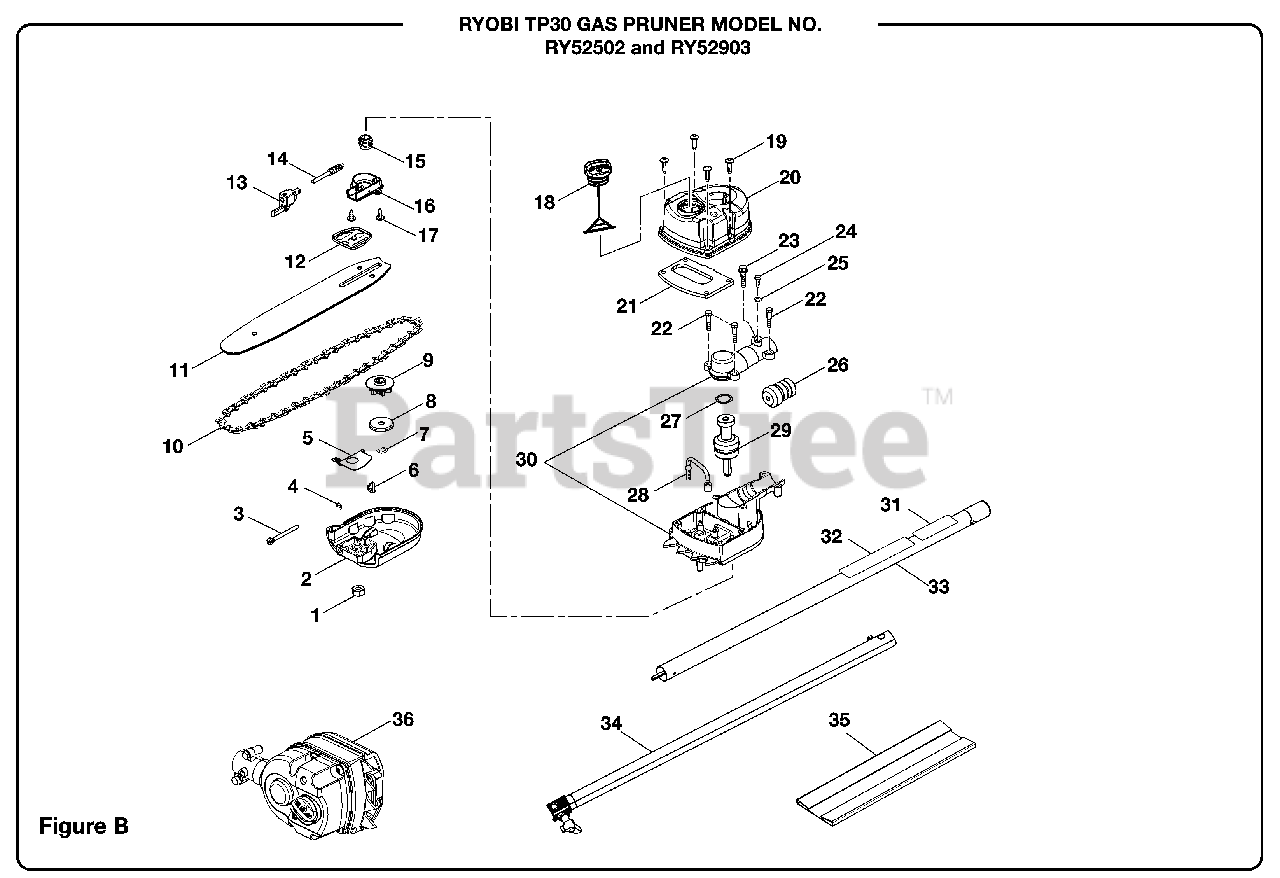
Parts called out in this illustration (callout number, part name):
1	HEX NUT (M8)
2	BAR CLAMP ASSEMBLY
3	GUIDE BAR ADJUSTMENT SCREW (M5 X 50 mm)
4	RETAINING RING (4 mm)
5	GUIDE BAR PLATE
6	GUIDE BAR ADJUSTING PIN (M5)
7	E-RING (6 mm)
8	CUPPED WASHER
9	SPROCKET
10	CHAIN (3/8,.043, 10)
11	GUIDE BAR
12	BAR PAD PLATE
13	OIL PUMP SEAL ASSEMBLY
14	OIL PINION GEAR & PLUNGER
15	WORM GEAR
16	OIL PUMP HOUSING W/CAM PIN ASSEMBLY
17	SCREW (M5 X 13 mm)
18	OIL CAP WITH RETAINER (PKG.)
19	SCREW (M5 X 18 mm)
20	OIL TANK COVER ASSEMBLY
21	OIL COVER GASKET
22	SCREW (M5 X 25 mm, SHOULDER SCREW)
23	SCREW (M5 X 25 mm)
24	SCREW (M5 X 15 mm)
25	SPRING WASHER (M5)
26	PINION GEAR ASSEMBLY
27	WAVY WASHER
28	PICK-UP TUBE ASSEMBLY
29	OUTPUT SHAFT ASSEMBLY
30	GEAR CASE AND COVER ASSEMBLY
31	EXPAND-IT LABEL
32	WARNING LABEL
33	PRUNER BOOM ASSEMBLY
34	INTERMEDIATE BOOM ASSEMBLY
35	BLADE COVER
36	PRUNER GEAR HEAD
